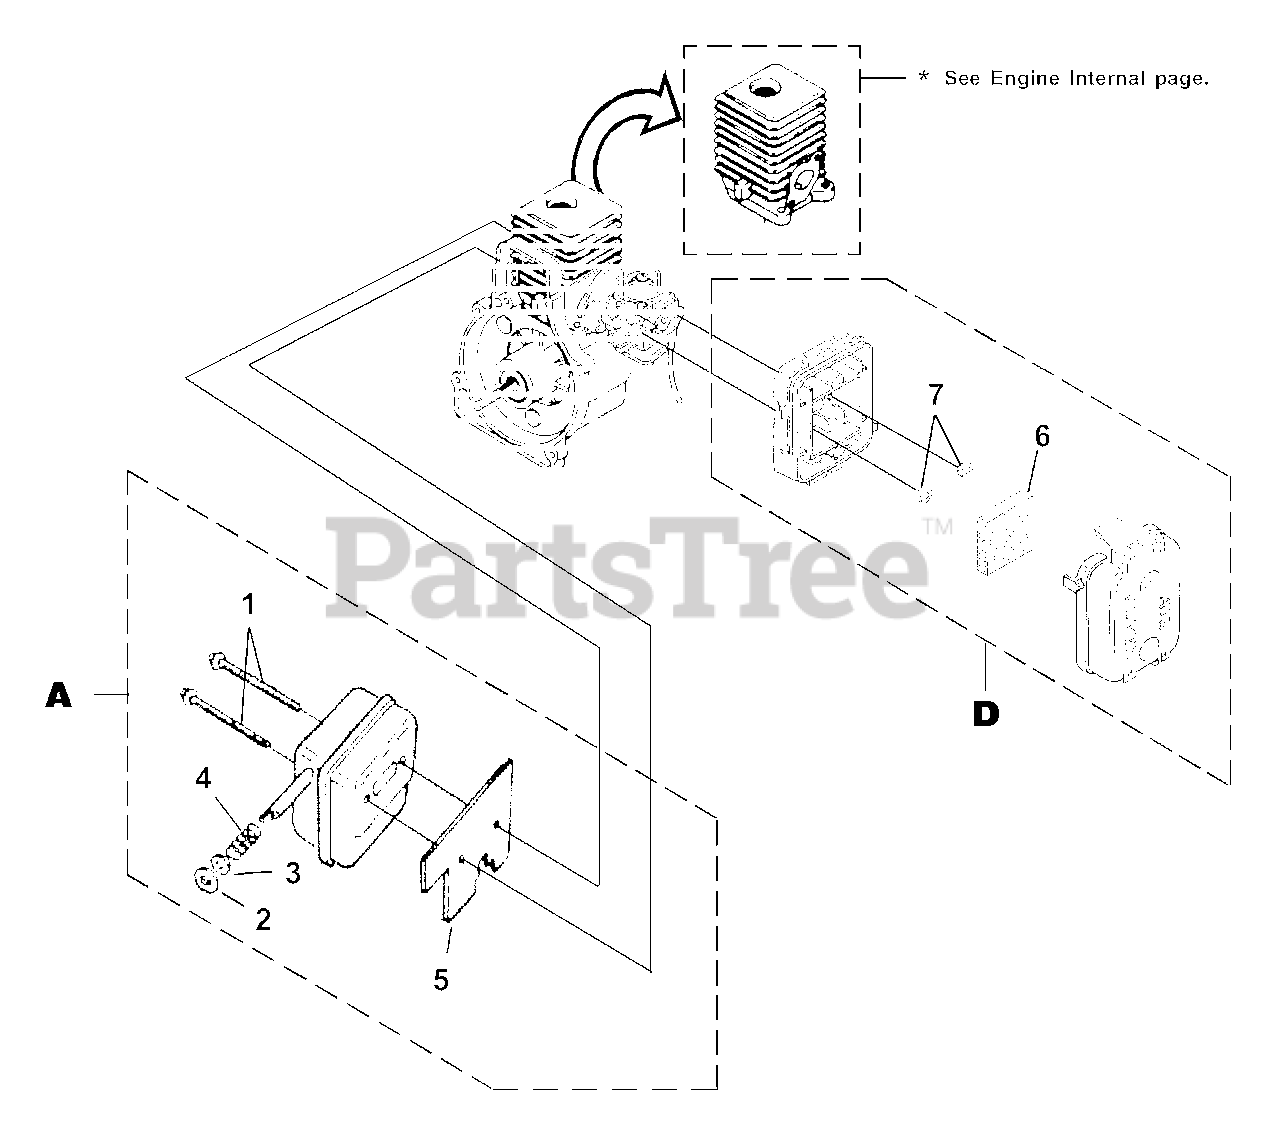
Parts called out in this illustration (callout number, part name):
1	SCREW-Sems Hex Hd. (10-24 x 2 1/2")
2	WASHER-Insulating
3	WASHER-Flat
4	SPRING-Compression
5	GASKET-Muffler
6	AIR FILTER
7	NUT-Hex (10-24)
A	MUFFLER-Complete
D	AIR FILTER KIT
